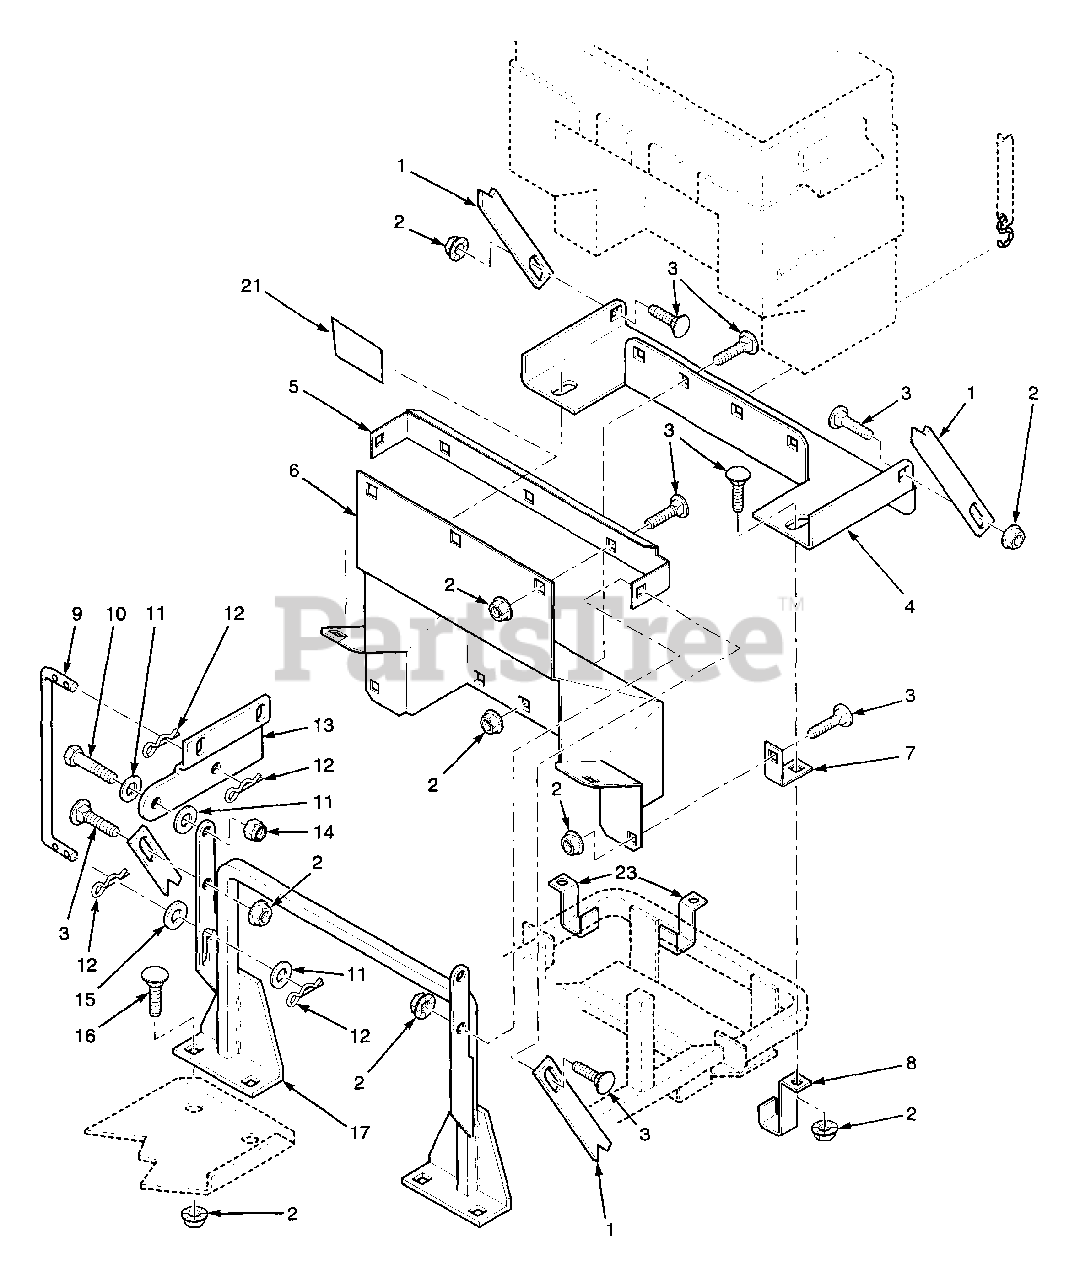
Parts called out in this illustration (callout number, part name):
1	Brace
2	Nut, 5/16-18 Serrated Flange
3	Bolt, 5/16-18 x .75" Carriage
5	Mount Guard
6	Debris Guard W/Decal
7	Bracket, Lower
8	Clamp, Tray
9	Rod, Cover Support
10	Bolt, 3/8-16 x 1.50"
11	Flat Washer, 3/8 (.391 x .938 x .105)
12	Hair Pin, .080 x 1.19
13	Hinge, Right Hand
14	Nut, 3/8-16 Elastic Stop
15	Flat Washer, 3/8 (.375 x 2.00 x .060)
16	Bolt, 5/16-18 x 1.00"
17	Support Frame Weldment
21	Decal, Hot Engine
